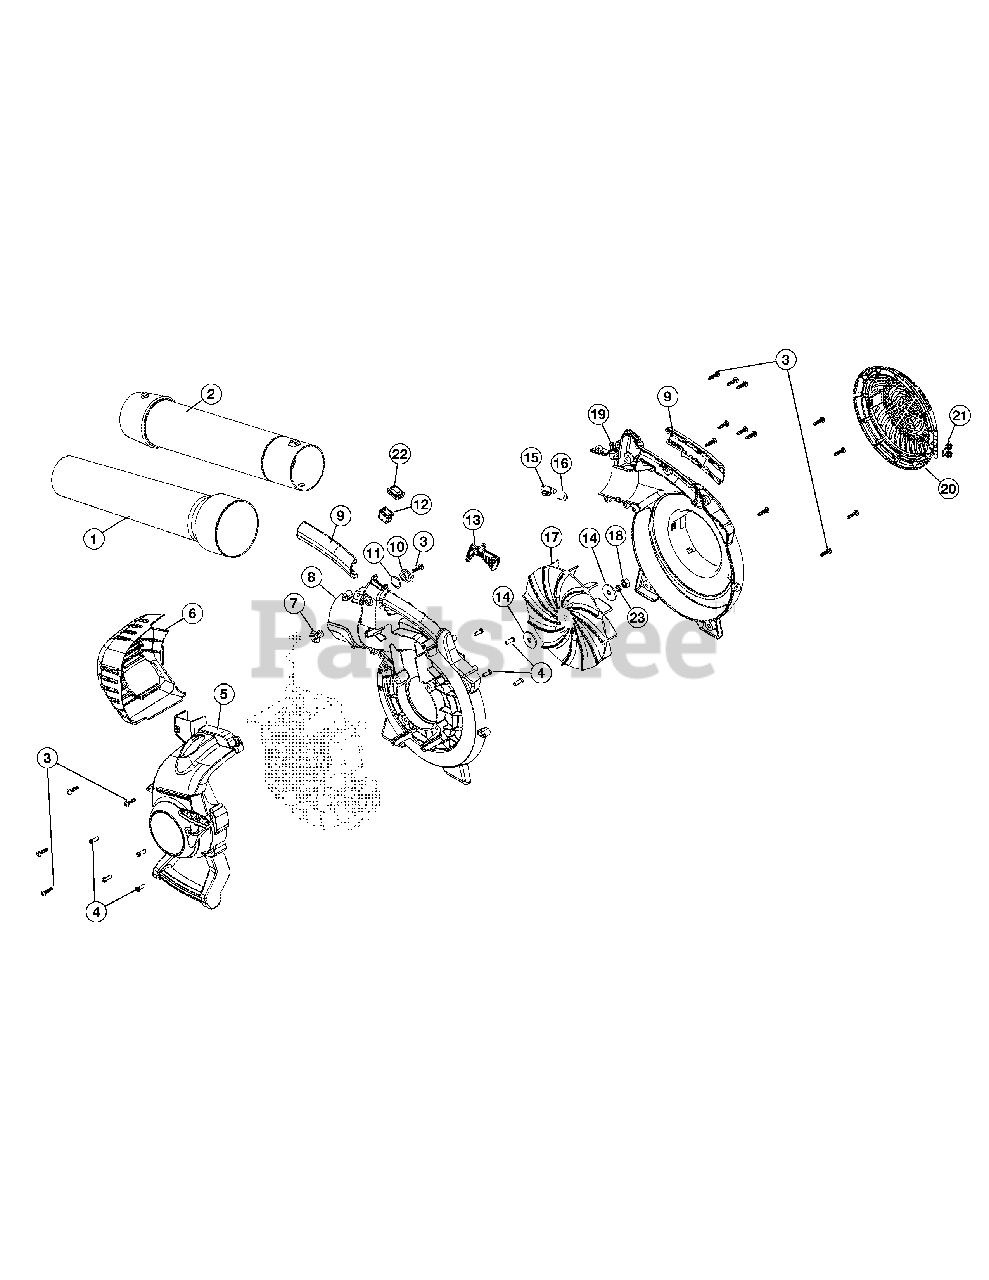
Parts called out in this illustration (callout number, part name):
1	Lower Tube
2	Upper Tube
4	Screw
5	Engine Cover Assembly
6	Muffler Cover Assembly
7	Outer Trigger Lock
8	Impeller Housing
9	Handle Grips
10	Inner Trigger Lock
11	Wavey Washer
13	Throttle Trigger
15	Latch Tube
16	Latch Spring
19	Impeller Housing
20	Intake Cover
22	Switch Cover
23	Lock Washer
